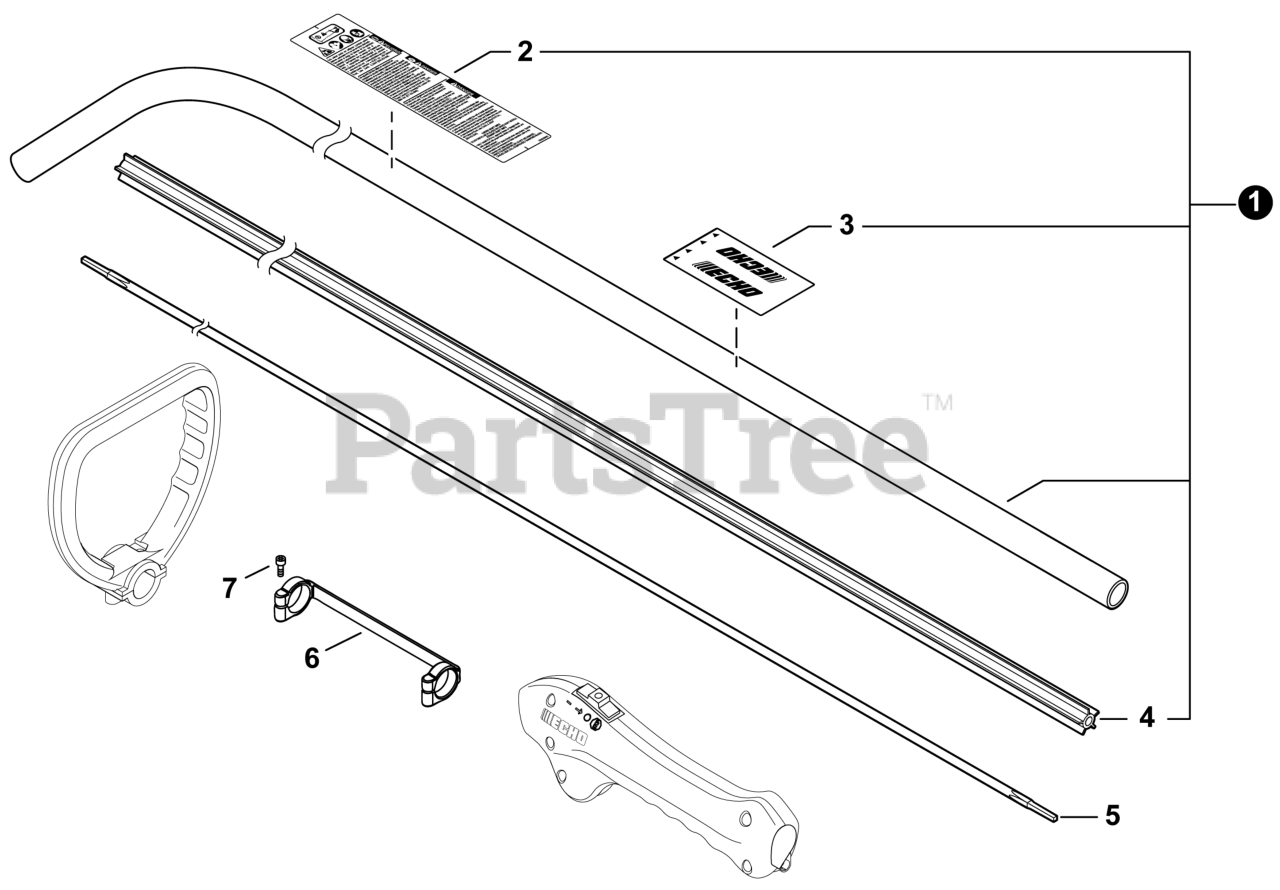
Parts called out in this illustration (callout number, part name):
1	MAIN PIPE ASSY
2	LABEL - CAUTION
3	LABEL - HANDLE LOCATION
4	LINER - FLEXIBLE
5	DRIVESHAFT - FLEXIBLE
6	COLLAR
7	BOLT, TORX 4x20
